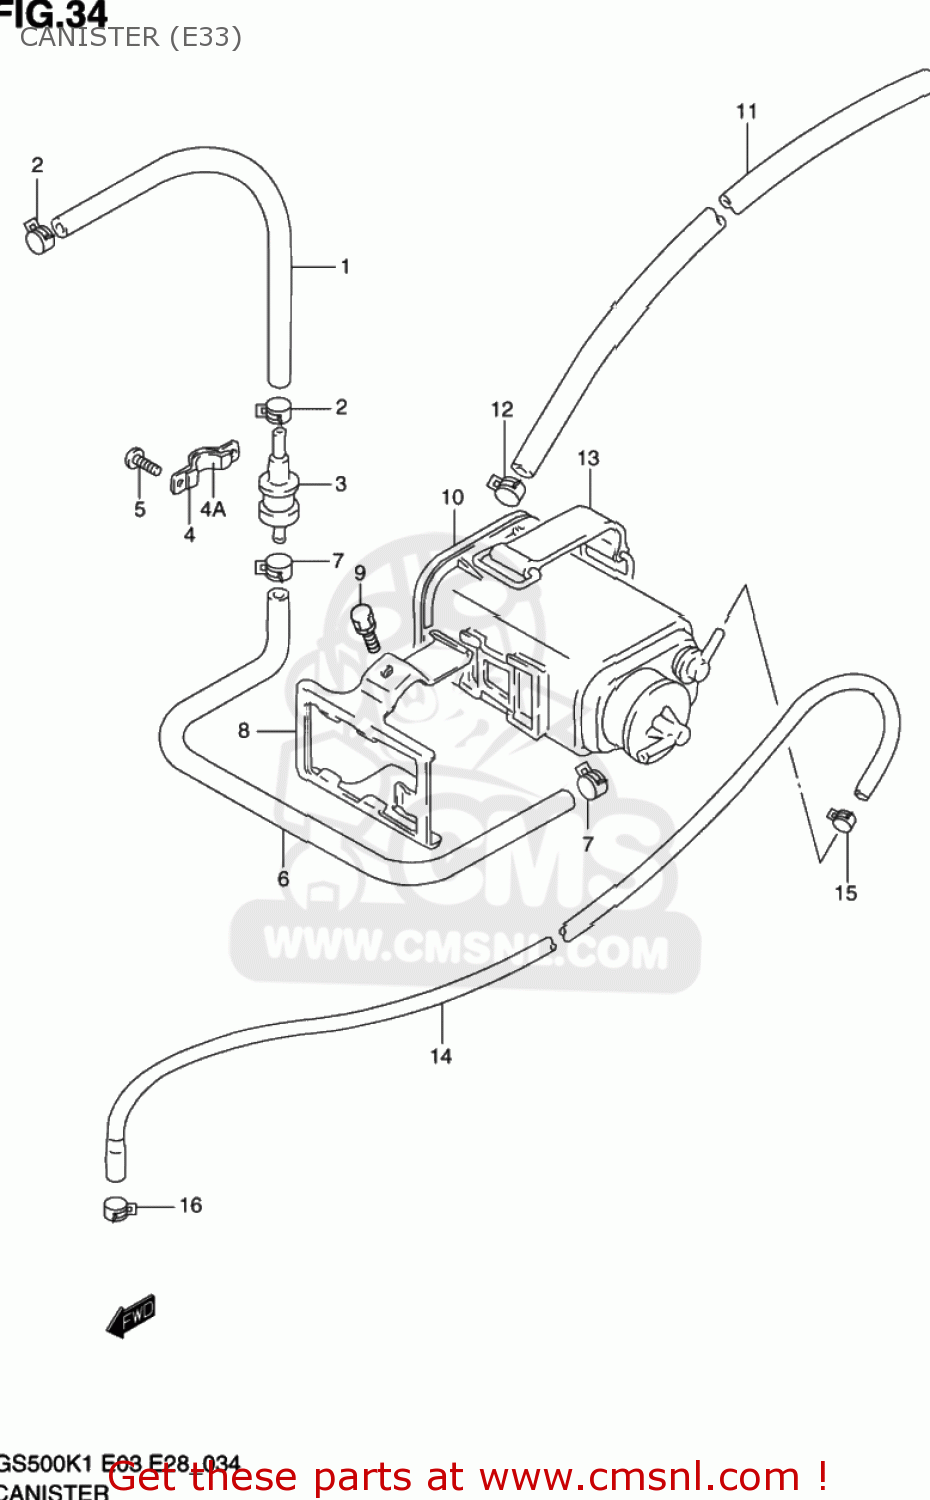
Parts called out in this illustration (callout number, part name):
1	HOSE(5.4X11.4X600)
2	CLIP
3	VALVE,FUEL TANK BREATHER
4	PLATE,FUEL TANK BREATHER NO.2
4A	CUSHION
5	SCREW
6	HOSE(5.4X11.4X350)
7	CLIP
8	PLATE,CSTR FITING
9	BOLT
10	CANISTER ASSY,CHARCOAL
11	HOSE(7X12X600)
12	CLIP
13	BAND
14	HOSE(3.5X7.5X600)
15	CLIP
16	CLIP
